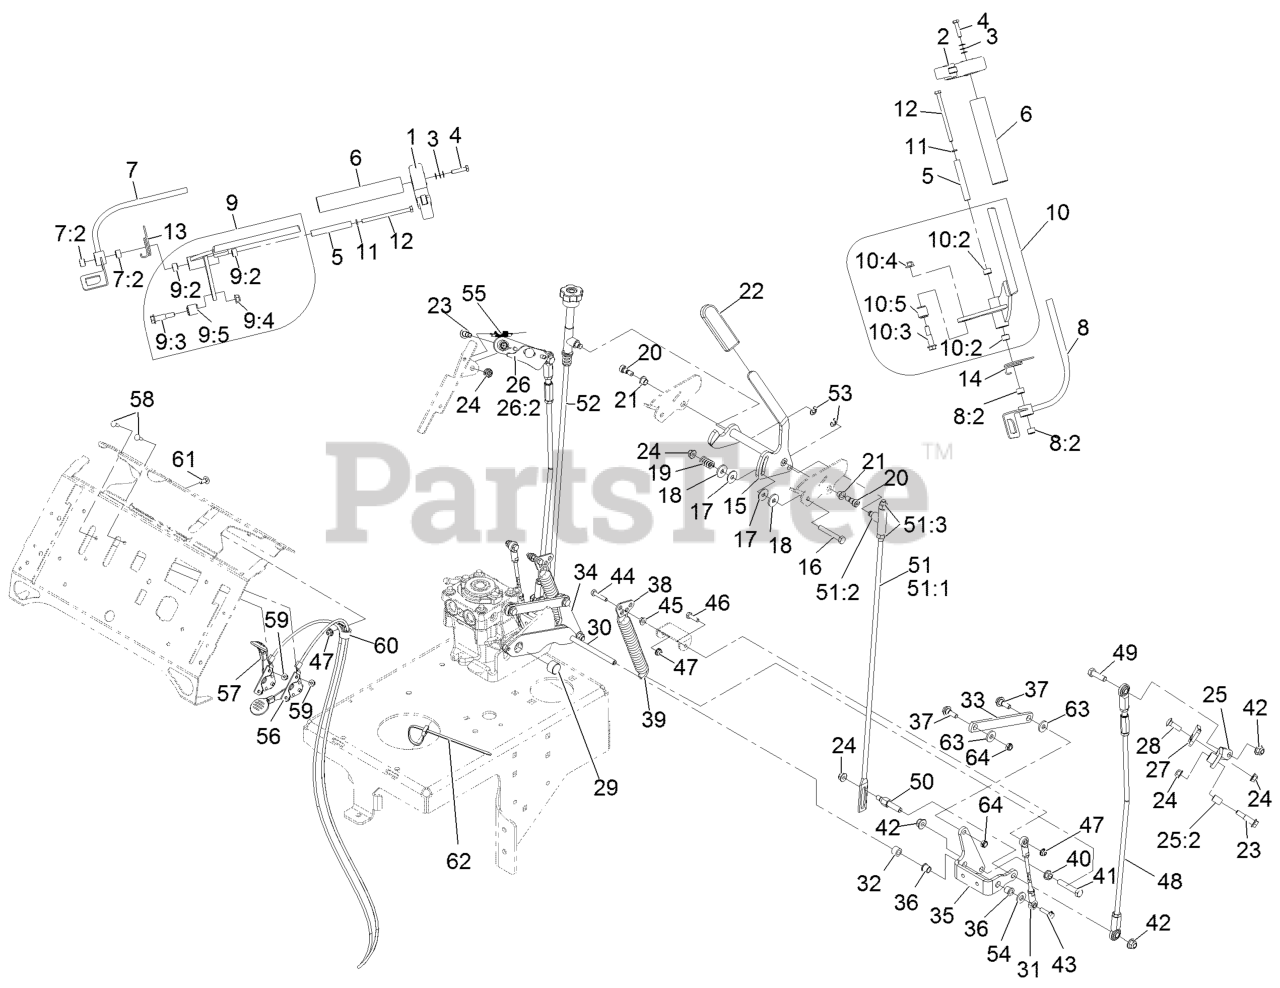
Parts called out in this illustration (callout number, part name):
1	ASM,LATCH RH THUMB
2	ASM,LATCH LH THUMB
3	WASHER-SPRING
4	SCREW-HH
6	GRIP-BAR, HANDLE
7	OPC-W/BUSHING, RH
7:2	BUSHING-SLEEVE
8	OPC-W/BUSHING, LH
8:2	BUSHING-SLEEVE
9	ASM, CONTROL-RH
9:2	BUSHING-SLEEVE
9:3	SCREW-SHOULDER
9:4	NUT-HF, NI
9:5	ASM, ROLLER
10	ASM, CONTROL
10:2	BUSHING-SLEEVE
10:3	SCREW-SHOULDER
10:4	NUT-HF, NI
10:5	ASM, ROLLER
11	SCREW-HH
12	SCREW-HH
13	SPRING, TORSION
14	SPRING, TORSION
15	SPEED CONTROL ASM
16	SCREW-HH
17	WASHER-FRICTION
18	WASHER-FRICTION
19	SPRING-COMPRESSION
20	SCREW-HSH
21	BUSHING
22	GRIP-HANDLE, STEERING
23	SCREW-SHOULDER
24	NUT-HF, NI
25	ARM ASM-LEFT
25:2	SLEEVE-BEARING
26	ARM ASM -RIGHT
26:2	SLEEVE-BEARING
28	BOLT-CARR
29	PIN-BELLCRANK LINK RETAIN
30	BELLCRANK LINK ASM
31	ASM, LINK
32	SPACER-WHEEL
33	LINK-BELLCRANK, PUMP
34	BELLCRANK-LOWER, RT
35	BELLCRANK-LOWER, LT
36	BEARING
37	SCREW-SHOULDER
38	LINK, ADJUSTABLE
39	SPRING-EXTENSION
40	NUT-HHF, WHIZ
41	SCREW-HH
42	NUT-HF, NI
43	SCREW-HHF
44	SCREW-HH
46	SCREW-HH
48	ASM, ROD
49	SCREW-HH
50	STUD-CONTROL, SPEED
51	ASM, ROD LEFT
51:1	ROD, LEFT
51:3	NUT-HEX
52	ASM, ROD RIGHT
53	RING-RETAINING
54	WASHER-FRICTION
55	SPRING-EXTENSION
56	CONTROL-THROTTLE
57	CONTROL-CHOKE
58	BOLT-CARR
59	NUT-LOCK, FLANGE
60	CLAMP-CABLE
61	SCREW-CARR
62	TIE-CABLE
63	WASHER-FLAT
64	NUT-LOCK, NI
